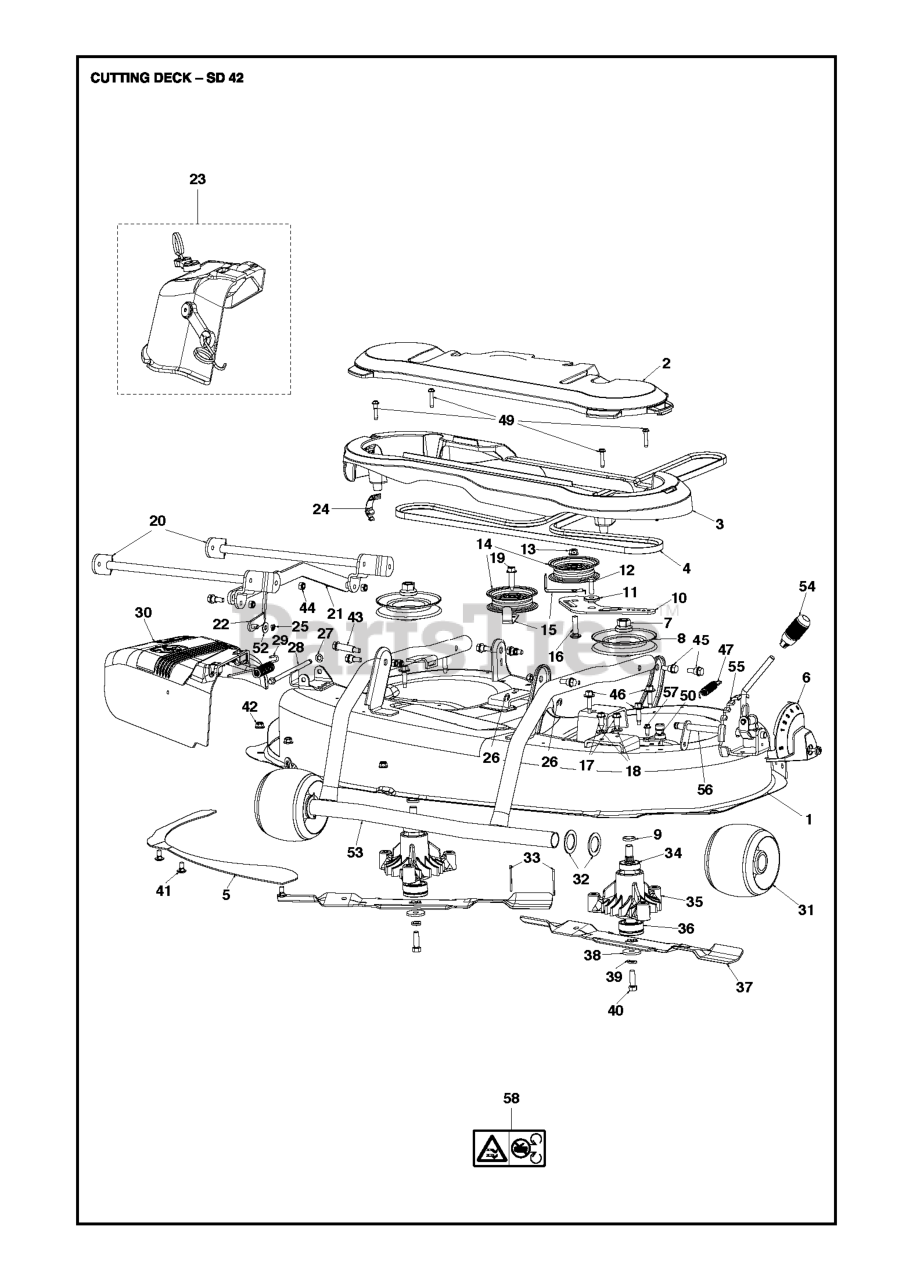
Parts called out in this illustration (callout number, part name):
1	DECK ATTACHMENT ASSY
2	COVER CUTTING DECK, UPPER
3	COVER CUTTING DECK, LOWER
4	BELT DRIVE 42 SD
5	BAFFLE.VORTEX
7	NUT.FLANGE.LOCK.TOP
8	PULLEY.DRIVEN.DECK.48'
9	WASHER.SPACER.MANDREL
10	BRACKET CLUTCHING ARM
11	WASHER
13	NUT LOCK FLG 3/8-16 UNC
14	FLAT IDLER PULLEY
15	KEEPER, BELT IDLER
16	BOLT.3/8-16X1.50
17	SCREW 5/16-18X1
18	WASHER
19	SCREW 3/8-16 X 1-1/2
22	LIFTING ARM
23	COVER ASM.MULCH/HDW.DLX.42"
24	BUCKLE ORANGE
25	RETAINER CLIP
26	RETAINING RING
27	NUT PUSH M
28	ROD.HINGE
29	SPRING.TORSION.DEFLECT
30	DEFLECTOR 42
33	COTTER PIN
35	HOUSING.MANDREL.44/46" VENT
36	SHAFT.ASM.W/BEARING
37	42" HI-LIFT BLADE
38	WASHER.BLADE
39	WASHER, LOCK 3/8
40	BLADE BOLT
41	BOLT
42	NUT.71038.31-18.HEX.NYLOCK
43	COLLAR SCREW 30 X 13
44	LOCKNUT M8
46	SCREW, WASHER HEAD
47	SPRING RETURN
49	SCREW.HXWH.THDRL.1/4-20X1-1/4
50	PORT.WASHOUT
52	WASHER.20X8.5
53	FRAME TUBE
56	RP LEVER ASSY SD42
57	SCREW.1/4-20X5/8
